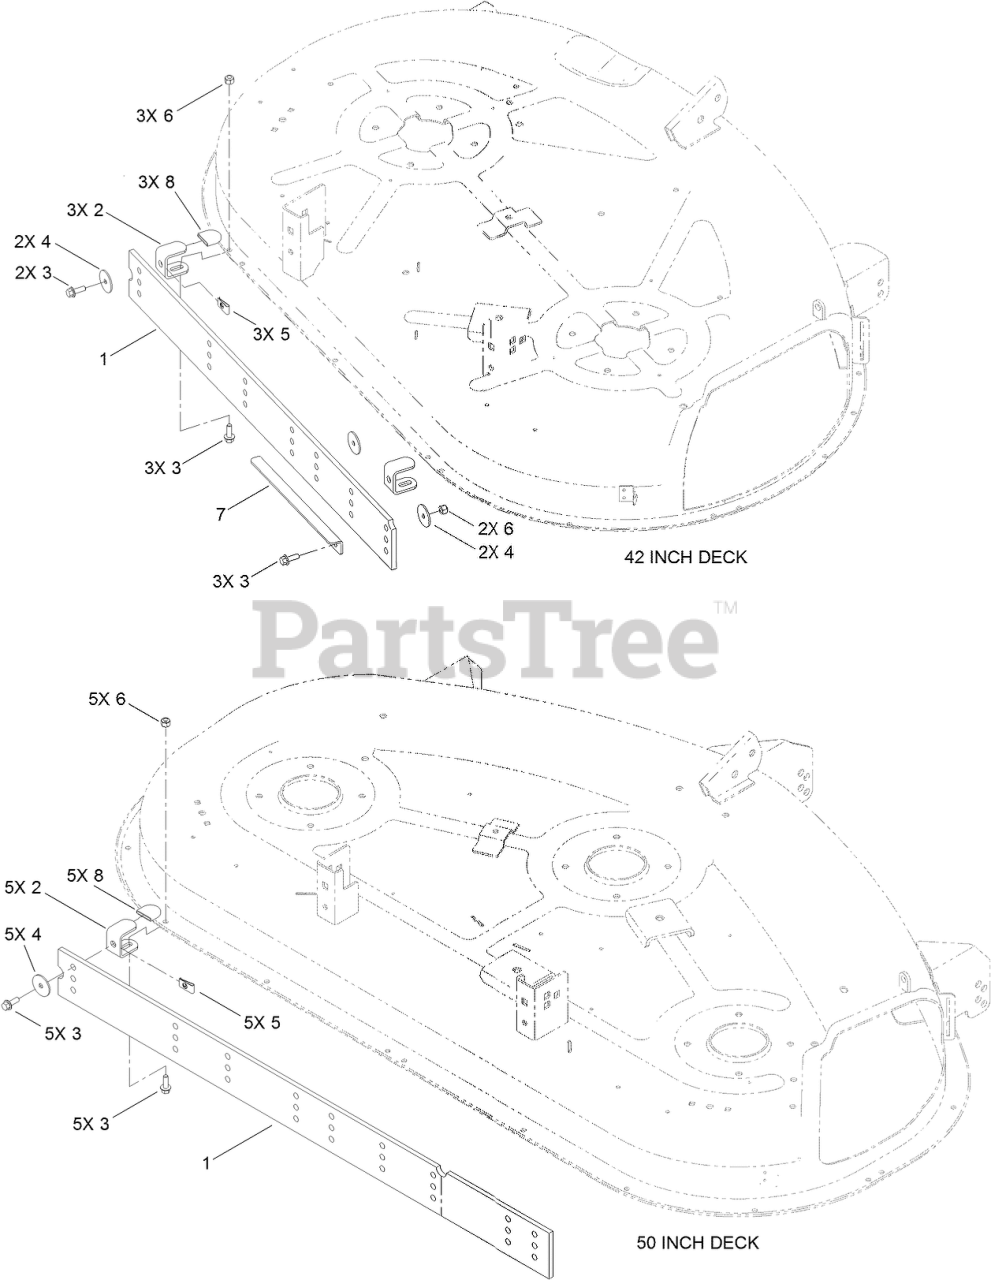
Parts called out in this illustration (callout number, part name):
2	BRACKET-MOUNTING
3	SCREW-HHF
4	WASHER-FLAT
5	NUT-SPEED
6	NUT-LOCK, NI
